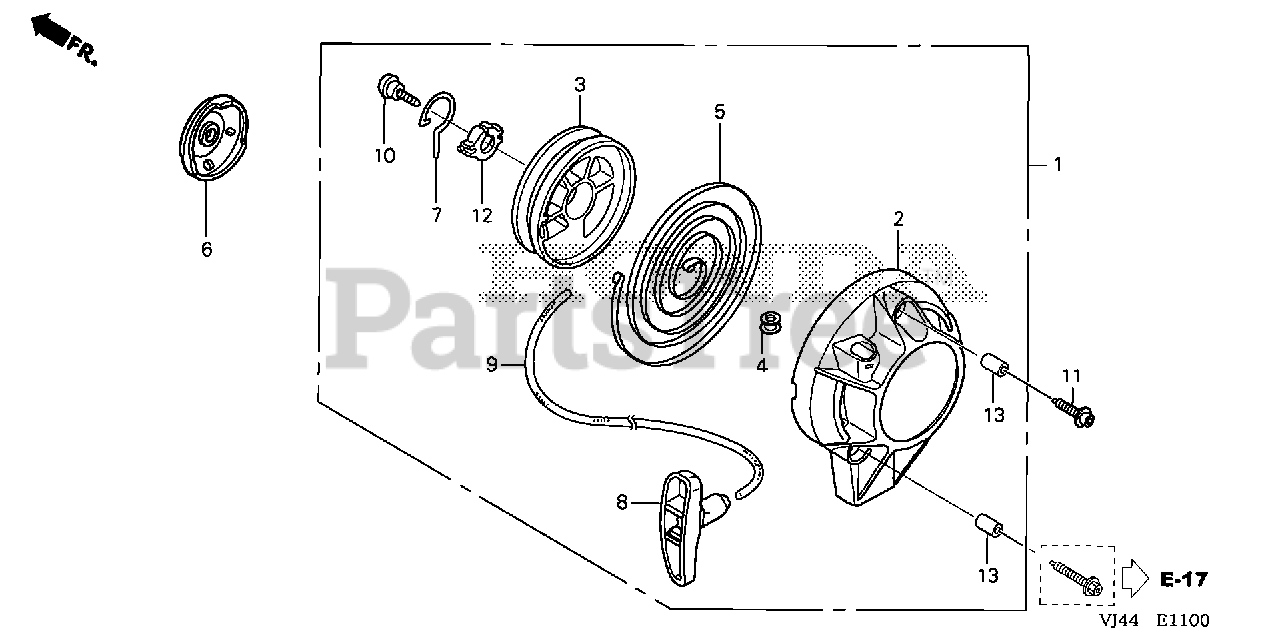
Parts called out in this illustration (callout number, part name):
1	STARTER ASSY., RECOIL (FOR U.S.A.)
1	STARTER ASSY., RECOIL
2	CASE, RECOIL STARTER
3	REEL, RECOIL STARTER
4	GUIDE, ROPE
5	SPRING, RECOIL STARTER
6	PULLEY, RECOIL STARTER
8	KNOB, RECOIL STARTER
9	ROPE, RECOIL STARTER
10	SCREW, SETTING
11	BOLT, SOCKET (5X16)
13	COLLAR A, HEAD COVER
